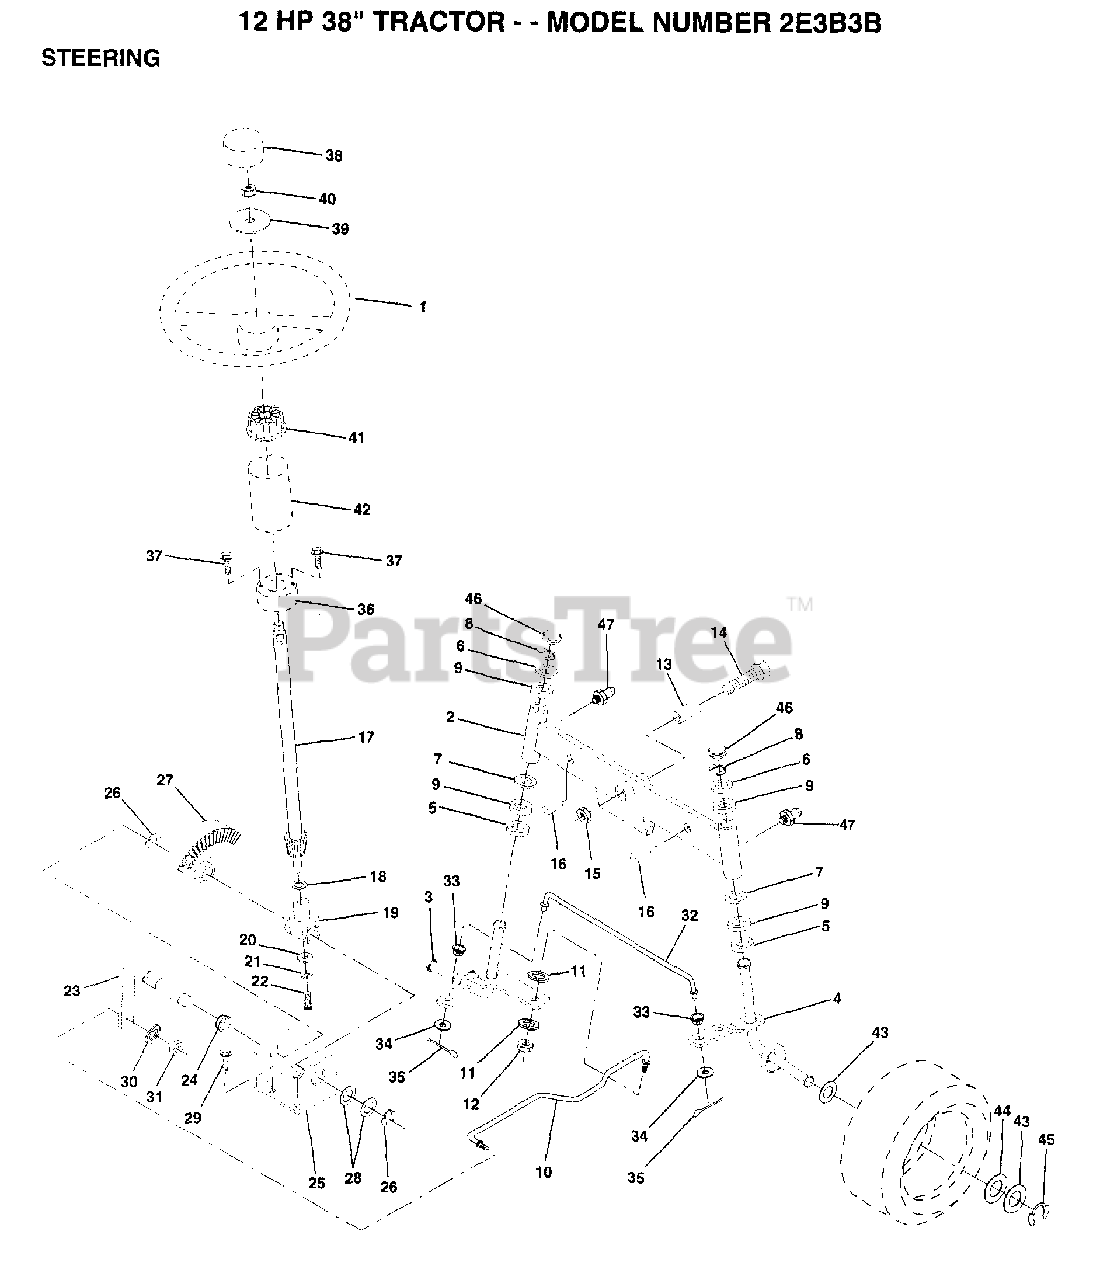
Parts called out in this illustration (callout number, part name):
2	AXLE ASM FRONT
3	SPINDLE LH
4	SPINDLE RH
5	WASHER .T
6	WASHER
7	WASHER
8	RING
9	COL. SRTG. BEAR.
11	LOCKWASHER
13	BEARING
14	BOLT HEX 5/8-11
15	"NUT-LOC,FLANGE LT"
16	AXLE PIN
17	SHAFT ASM
18	THRUST WASHER
19	SUPPORT.SHAFT
21	LOCKWASHER
22	"SCREW,SPECIAL"
24	NYLINER T
25	"BRKT,STEERING"
26	RING
27	GEAR SECTOR
28	WASHER .T
29	SCREW
30	LOCKWASHER
32	TIE ROD
33	BUSHING.DRAGLINK
34	WASHER
35	COTTER PIN
38	ST WHL INSERT CAP
39	WASHER T
40	GRIPCO NUT
41	ADAPTER-WHEEL LT
42	"TUBE, STR SHAFT"
43	WASHER
44	WASHER
45	RING
46	CAP
47	ZERK M
